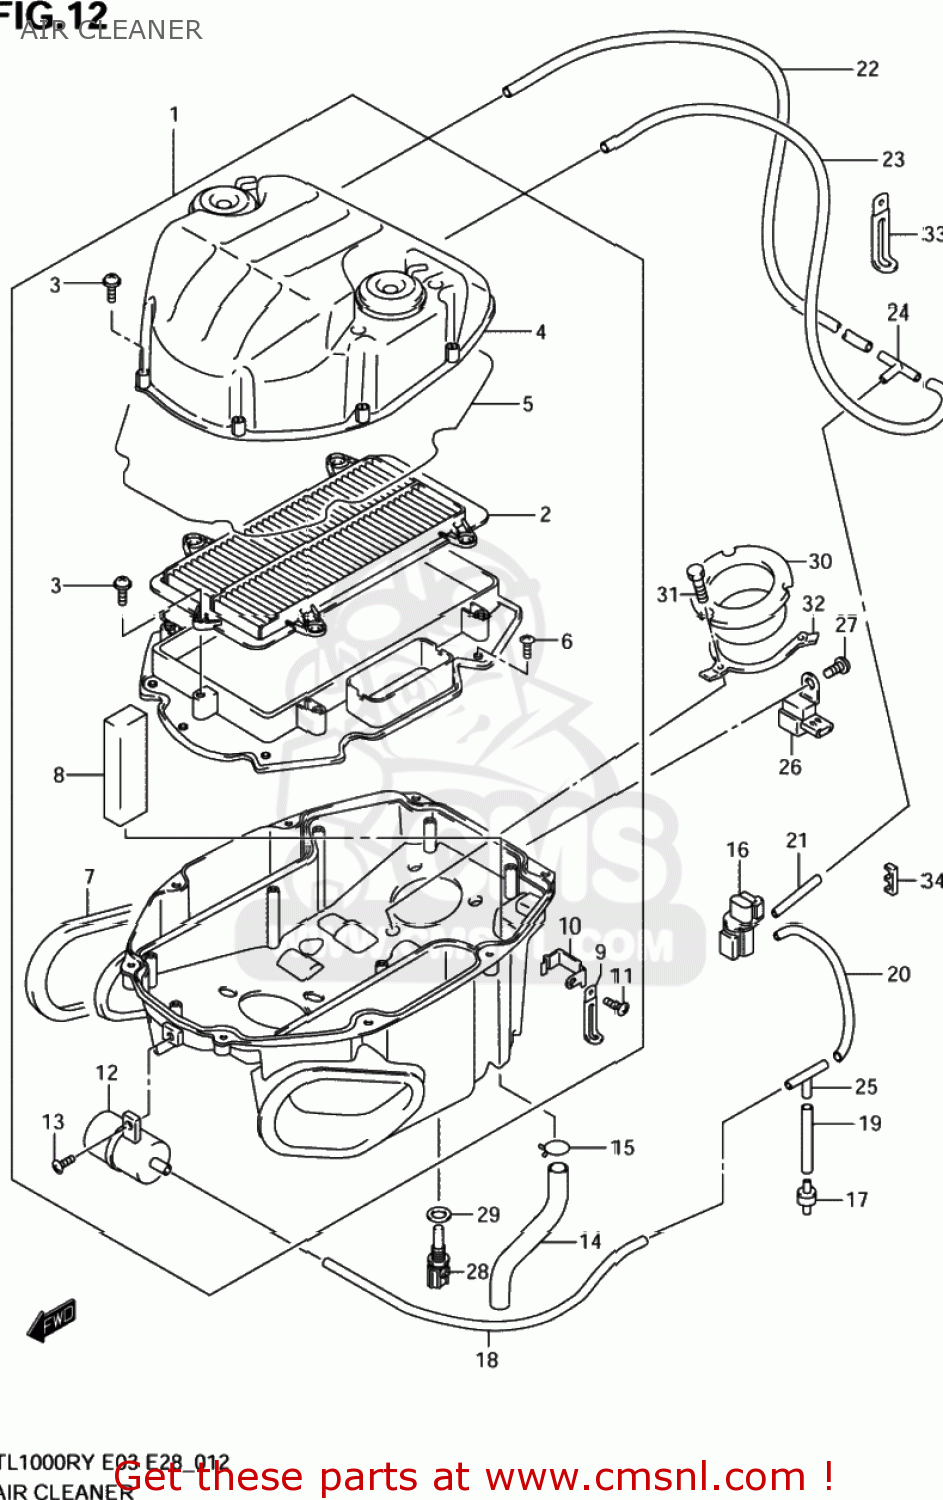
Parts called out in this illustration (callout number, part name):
1	CLEANER ASSY,AIR
2	FILTER,AIR CLEANER
3	SCREW,AIR CLEANER
4	CAP,AIR CLEANER
5	GASKET (NAS)
6	SCREW
7	CUSHION,DUCT
8	FILTER,BREATHER
9	CLAMP(L:65)
10	BRACKET,SOLENOID VALVE
11	SCREW 6X12
12	CHAMBER,VACUUM
13	SCREW
14	TUBE,BREATHER
15	CLIP
16	VALVE ASSY,3WAY SOLENOID
17	VALVE,CHECK
18	HOSE(3.5X7.5X600)
19	HOSE(3.5X7.5X600)
20	HOSE(3.5X7.5X600)
21	HOSE(3.5X7.5X600)
22	HOSE(3.5X7.5X600)
23	HOSE(3.5X7.5X600)
24	3WAY,VACUUM HOSE
25	3WAY,VACUUM HOSE
26	SENSOR,BOOST
27	SCREW 6X12
28	SENSOR,WATER TEMP
29	GASKET(12X17X1) (NAS)
30	FUNNEL,AIR CLEANER
31	BOLT(6X20)
32	WASHER,AIR FUNNEL
33	CLAMP(L:65)
34	CLAMP
